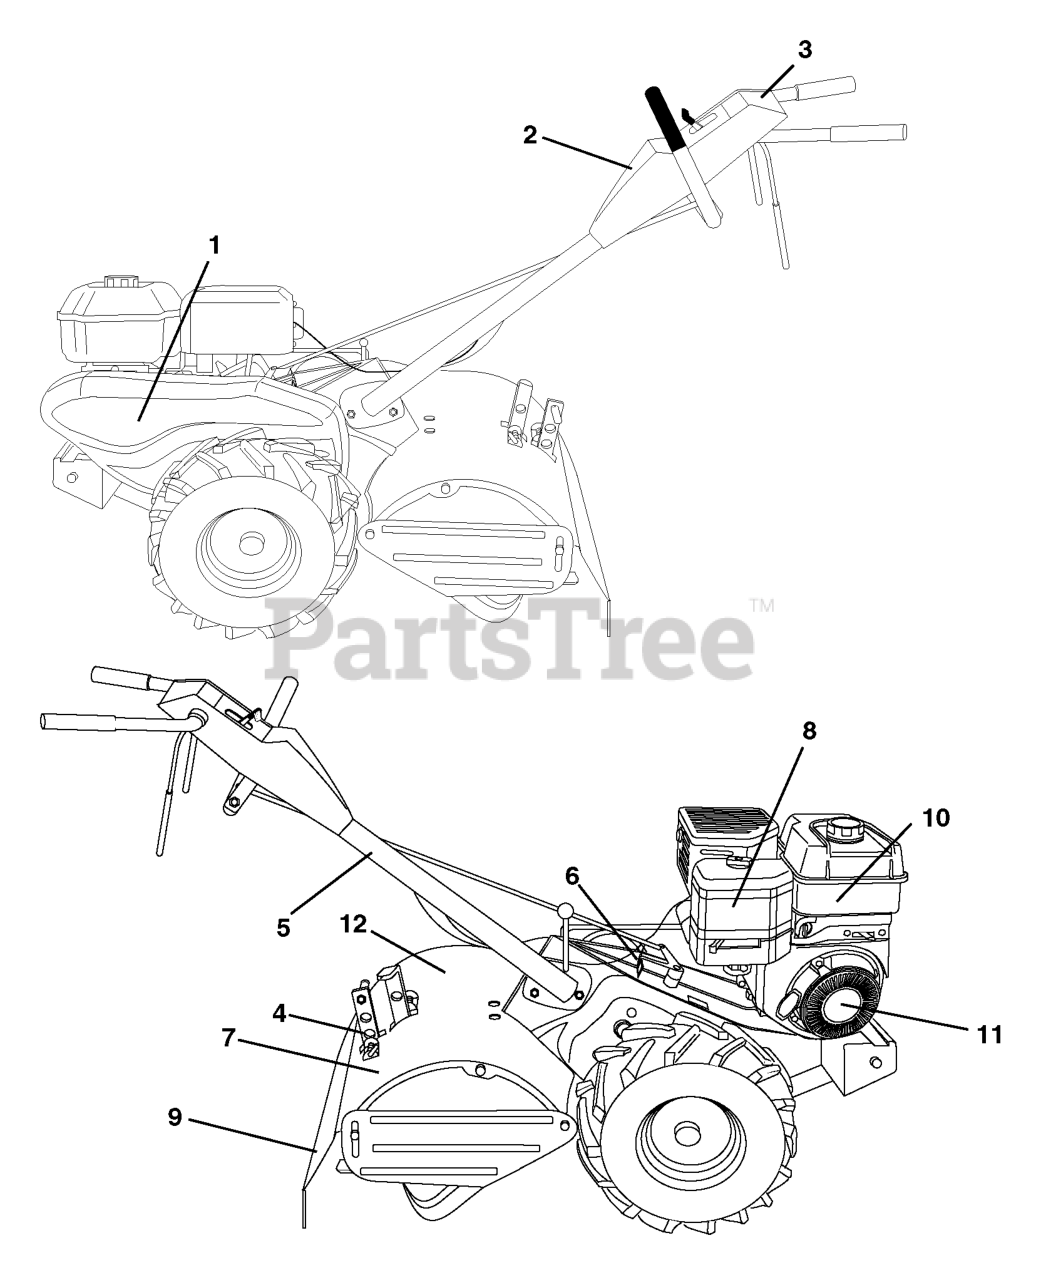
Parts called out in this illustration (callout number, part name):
2	DECAL.CONSLE.700.DRT
3	DECAL.CONSOLE.DRT.HU
4	DECAL.SHIELD.TN.17.D
5	DECAL TI (2 2)
6	DECAL.SHIFT.INDICATOR.DRT
7	DECAL.REVERSE.HUSQ
8	DECAL.B&S.7HP
9	DECAL.DRT.WARN.ENG/F
10	DECAL.ENG.INTK.B&S.206CC
11	DECAL.REWIND
12	DECAL.FORWARD.HUSQ
